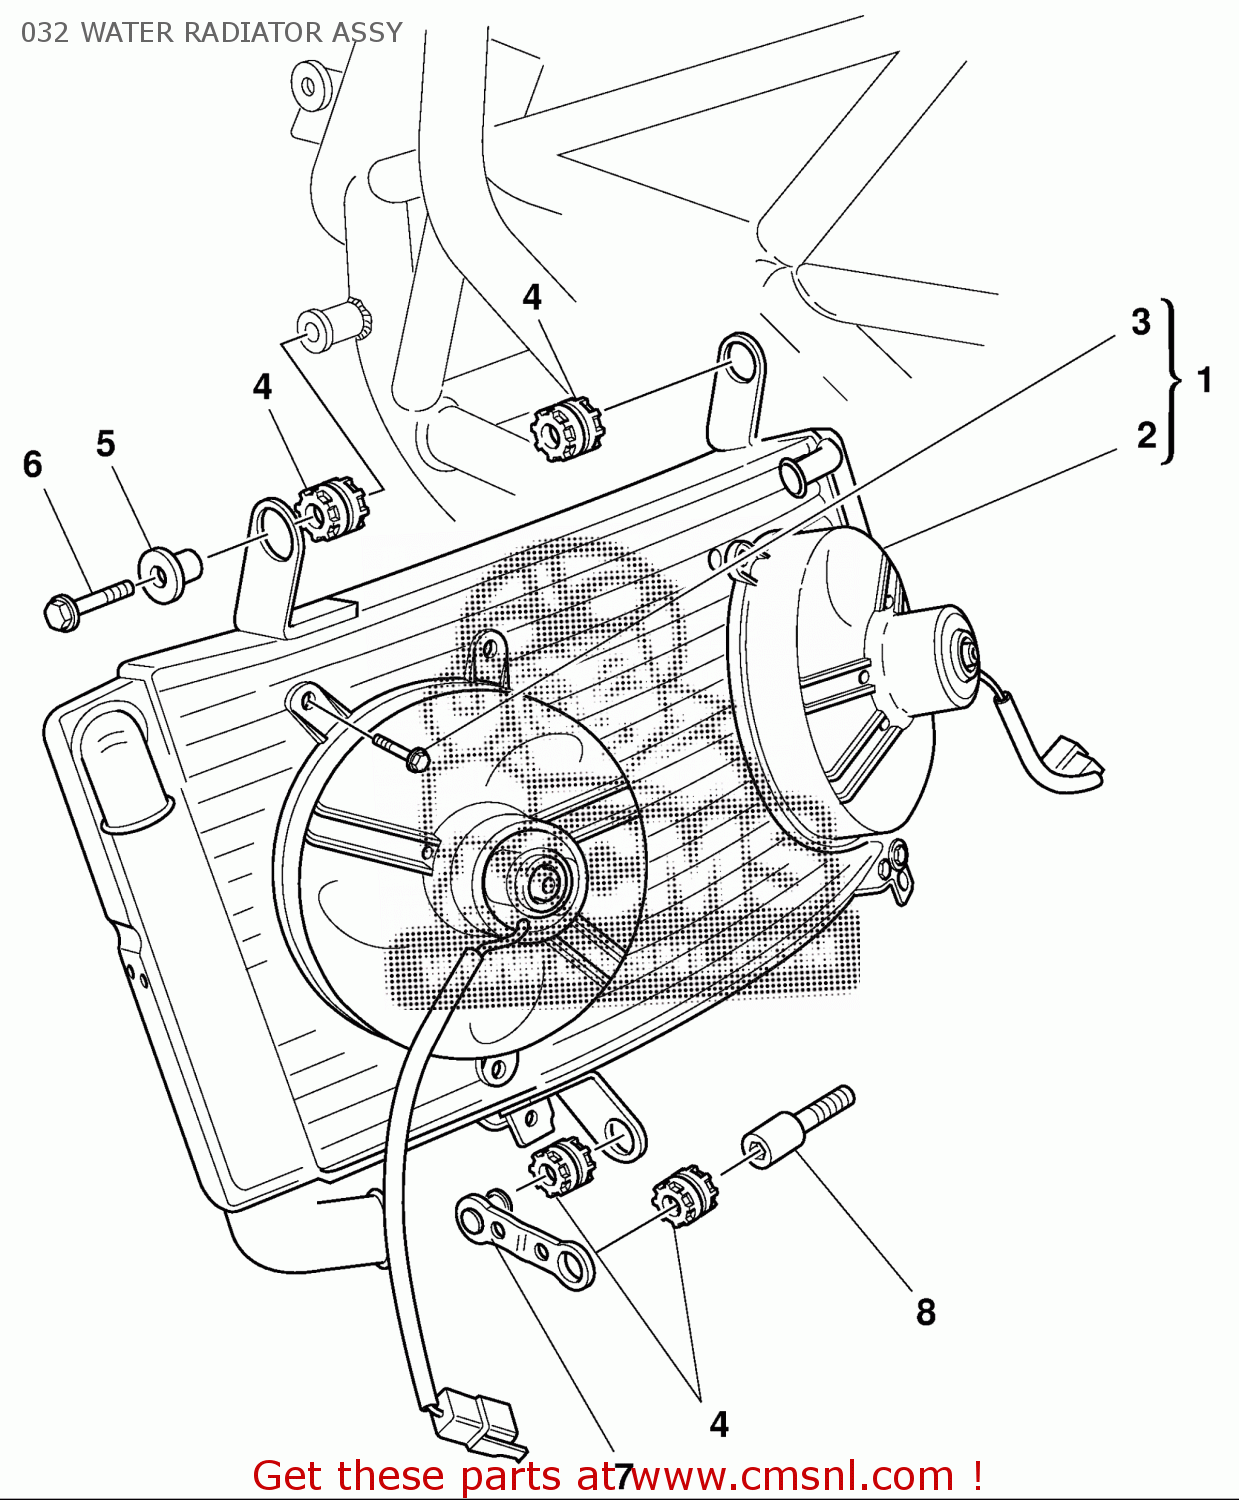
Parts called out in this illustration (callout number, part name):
1	WATER COOLER
2	ELECTRIC FAN
3	SCREW M6X10
4	VIBRATION DAMPER PAD
5	SPACER
6	SCREW TE M6X1.00X25 CH8
7	BRACKET
8	SCREW, SPECIAL
